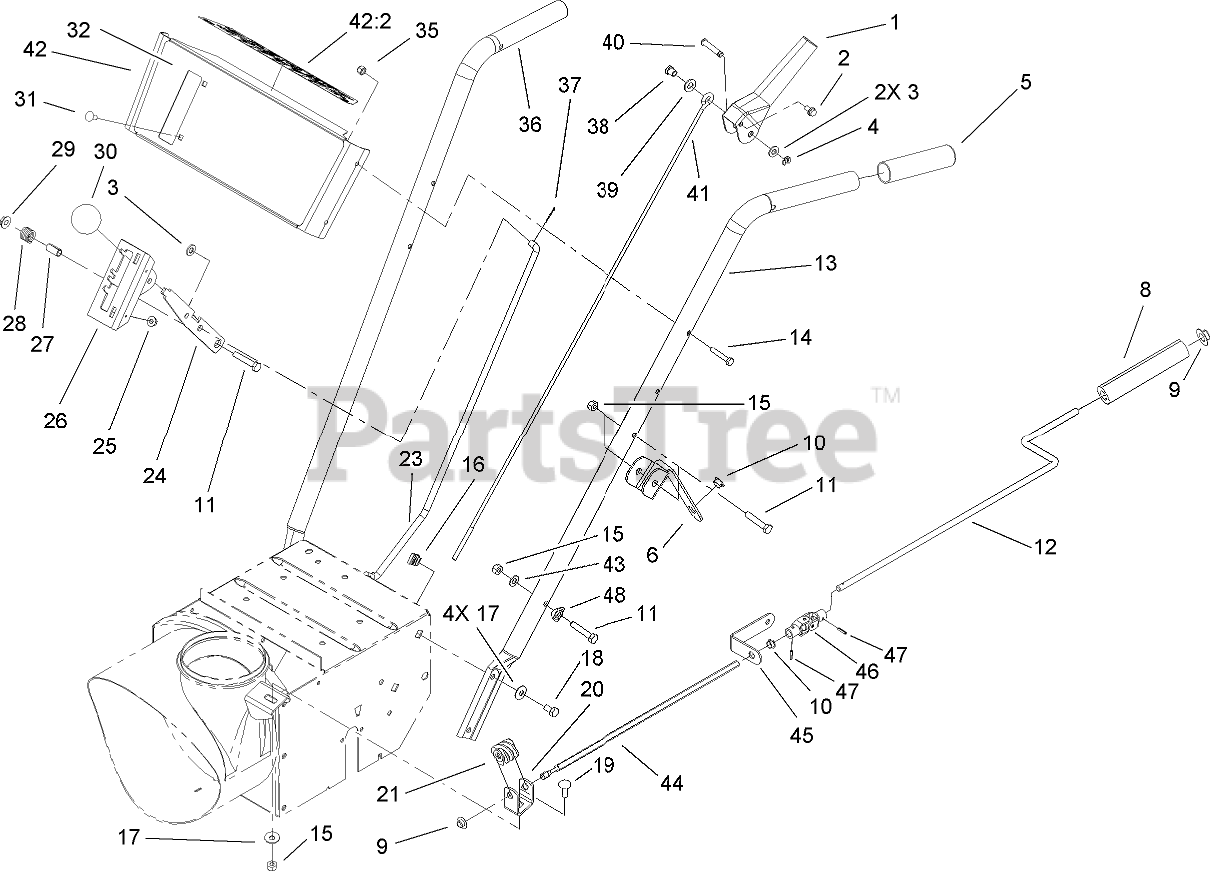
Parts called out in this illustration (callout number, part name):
1	HANDLE-CONTROL
2	SCREW-HHF
3	WASHER-PLAIN
4	RING-CLIP
5	GRIP-HANDLE
6	BRACKET-ROD, UPPER CHUTE
8	GRIP-CONTROL, CHUTE
9	RETAINER-PUSH ON
10	Bushing
11	SCREW-HH
12	ROD-CHUTE, UPPER
13	HANDLE-LEFT
14	SCREW-HH
15	NUT-LOCK, NI
17	WASHER-BELLEVILLE
18	SCREW-HH
19	SCREW-CARR
20	BRACKET-WORM
21	GEAR-WORM, CHUTE
23	ROD-SELECTOR, SPEED
24	Selector-Speed
25	NUT-HF
26	MOUNT-SELECTOR, SPEED
27	SPACER
28	SPRING
29	NUT-HF
31	SCREW-CARR
32	DECAL-ESCUTCHEON
35	NUT-LOCK, NI
36	HANDLE-RIGHT
37	PIN-COTTER
38	POST-MOUNTING, LINKAGE
39	WASHER-FLAT
40	PIN-LEVER, CONTROL
41	LINK-UPPER
42	ESCUTCHEON PANEL ASM
42:2	DECAL-ESCUTCHEON, BACK
43	WASHER-PLAIN
44	ROD-CHUTE, LOWER
45	BRACKET-ROD, LOWER
46	JOINT-UNIVERSAL
47	PIN-ROLL
48	WASHER
